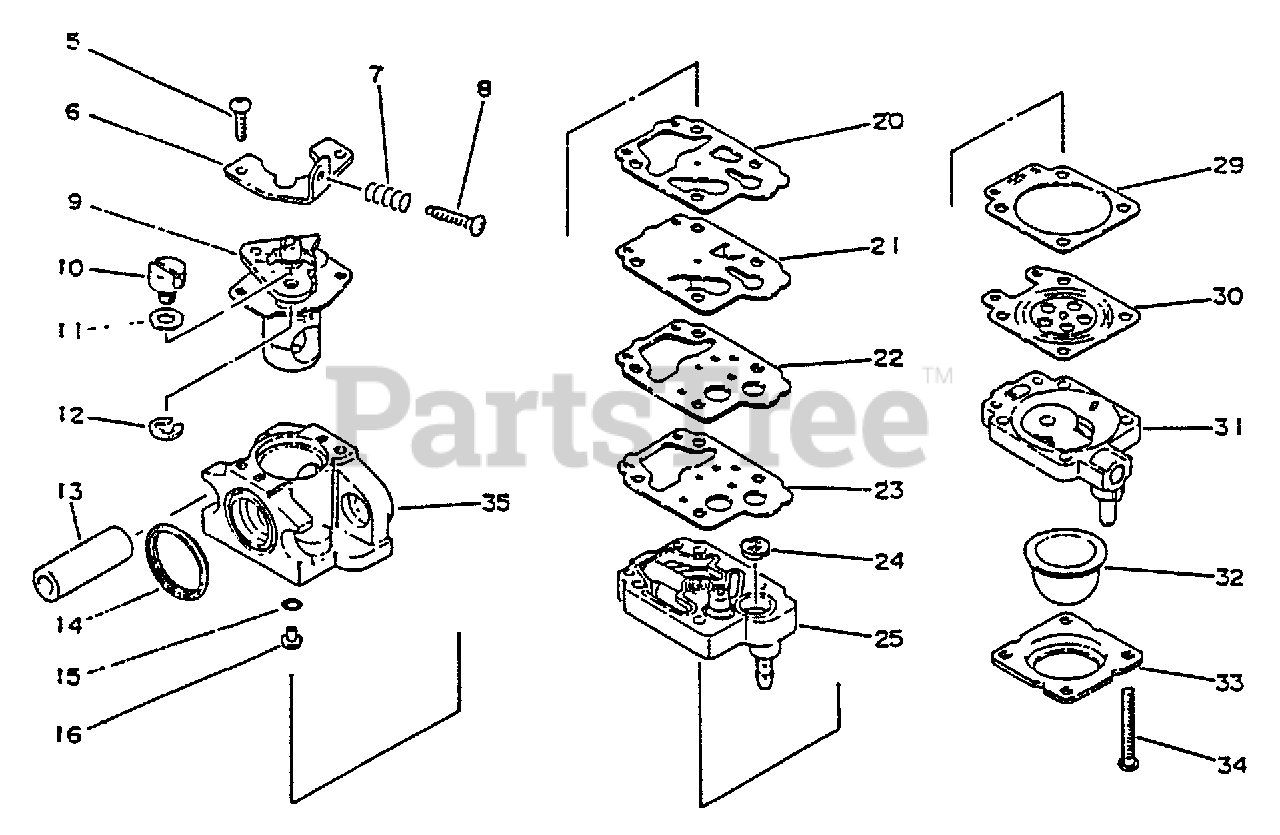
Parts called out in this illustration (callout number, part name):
6	BRACKET, THROTTLE CABLE
7	SPRING, IDLE ADJUST
8	SCREW, IDLE ADJUST
9	VALVE, THROTTLE
12	RING, RETAINING
13	SLEEVE, MOUNTING
14	REPAIR KIT
14	DIAPHRAGM/GASKET KIT
15	REPAIR KIT
16	REPAIR KIT
20	REPAIR KIT
21	REPAIR KIT
21	DIAPHRAGM/GASKET KIT
22	PLATE, PUMP
23	REPAIR KIT
24	REPAIR KIT
25	REPAIR KIT
29	REPAIR KIT
29	DIAPHRAGM/GASKET KIT
30	REPAIR KIT
30	DIAPHRAGM/GASKET KIT
31	BASE, PURGE
32	BULB, PURGE
33	RETAINER, PURGE BULB
35	BODY, CARBURETOR
